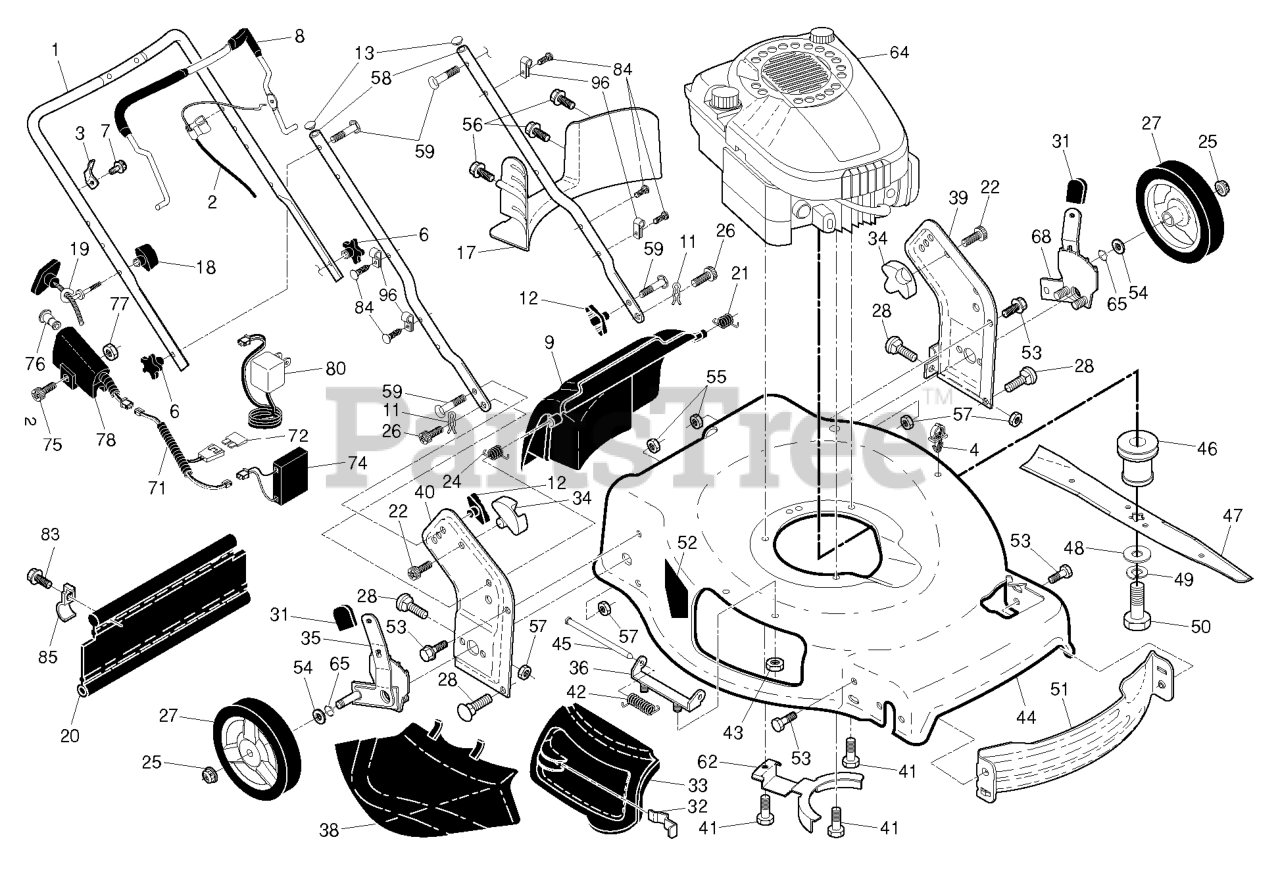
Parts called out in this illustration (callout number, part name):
1	HANDLE.UPPER.3.POS.BS.AW2.GREY
2	CABLE.ASM.ZONE.CONTROL
3	BRACKET.UPSTOP.RT
6	KNOB.HANDLE.PLASTIC.STAR.BLACK
8	BAIL.OVER.MOLD.ERGO.MZR.ORANGE
9	DOOR.REAR.ASM.22+.HUSQ.FG/RGD
11	COTTER.HAIRPIN.DOOR/HANDLE.PIV
12	KNOB, DEFLECTOR
13	PLUG.PLASTIC.7/8".14-20.GAUGE
17	BAFFLE.22PLUS.FGD.REAR.
18	T-KNOB.NEW ROPE GUIDE
19	GUIDE.ROPE.BLK.ZINC.CHROM
20	SKIRT.REAR.22PLUS.RGD/FGD.NEW
21	SPRING.LH.BLACK
22	SCREW.PAN.HEAD.#10
24	SPRING.RH.GRAY
25	NUT.HEX.FLANGE.3/8-16.LO(3 2)
26	SCREW,DOOR/HANDLE.PIVOT
27	WHEEL & TIRES ASSY, FRONT
28	BOLT
31	SELECTOR KNOB
32	LATCH.DOOR.ZINC
33	DOOR.MULCH.22 PLUS.HUSQ.GREY
34	BRACKET.GRASSBAG.ATTACHING.BLK
35	ADJUSTER.ASM.9POS.LW.RR/RGD.
36	BRACKET.ASM.HINGE.21.FWGD.
38	DEFLECTOR.CLIPPING.22.BLACK
39	BRACKET.ASM.HANDLE.LT.22+.GREY
40	BRACKET.ASM.HANDLE.RT.22+.GREY
41	BOLT 3/8-16X1-1/8
42	SPRING.TORSION
43	NUT.HEX.FLANGE.1/4
44	HOUSING.22+.FWD.MC.ZWO.ORANGE.
45	ROD.HINGE.21
46	ADAPTOR BLADE 25MM STAR
47	BLADE.22+4N1.2PIN.5STAR.(P07)
48	WASHER,HARDEN
49	LOCKWASHER
50	SCREW, HEX HD 3/8-24 X 1-3/8
51	BAFFLE.FRONT.22.PLUS
52	DANGER DECAL
53	BOLT.5/16HEX.WHS.HD
54	WASHER.FLAT.1/2
55	NUT.HEX.FLANGE.1/4
56	SCREW.HX.13X.750
57	NUT.FLANGE.5/16
58	HANDLE.LOWER.22+BT.2PC.GRY
59	BOLT, HANDLE 5/16-18X1.75
62	BRACKET.ENG/BELTKEEPER
65	O-RING..070X.487.NEOPRENE
68	ADJUSTER.ASM.9POS.LW.RL/RGD.FR
71	HARNESS.WB.BATTERY.FGD.22+
74	BATTRY.12VLT.22+.FGD.W/PAD AGM
75	BOLT.M6-1X40.T30
76	BUTTON.KEY.CYLINDER.BLACK
77	NUT.M6-1 NYLOC
78	RP CONTROLSH.BUTTON.START.22"
80	RP CHARGER.12V.0.1A
83	TAPPING SCREW
84	FASTENER.PUSH.O.250X0.783
85	BRACKET.SKIRT.22+.BZP
96	CLIP.CABLE.BLK
